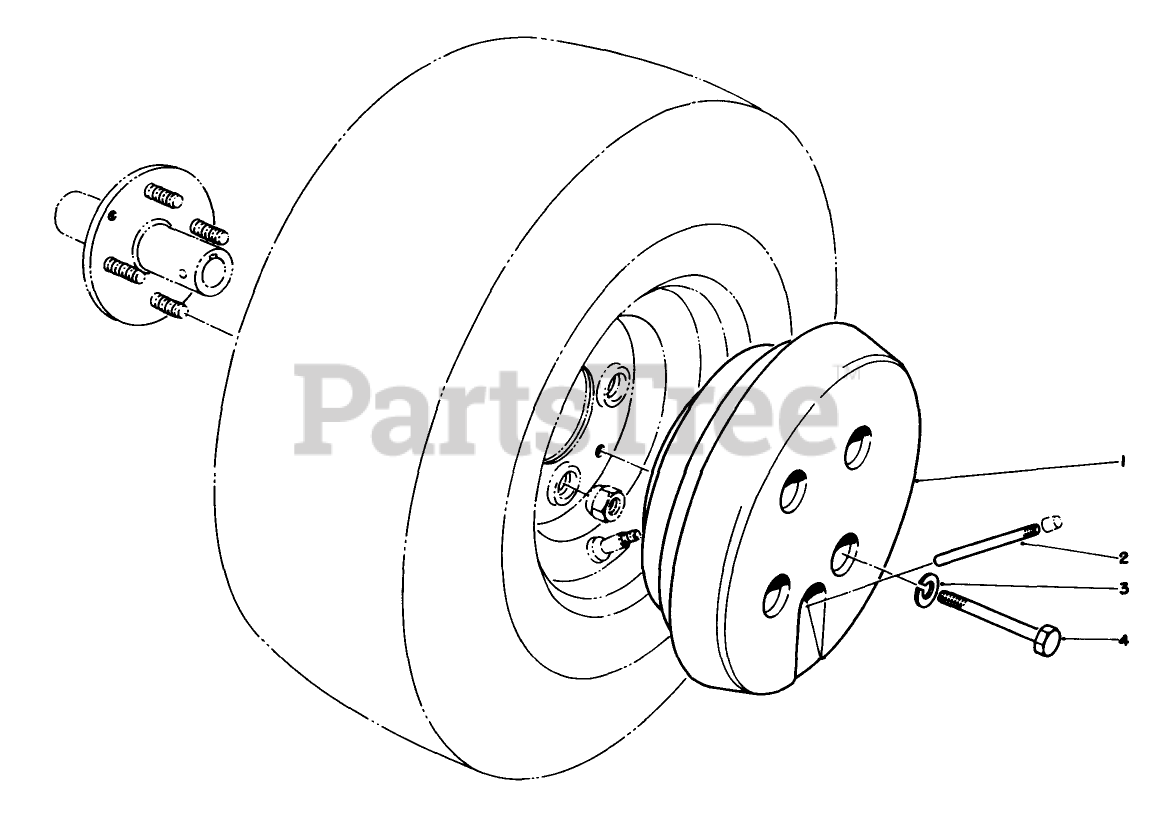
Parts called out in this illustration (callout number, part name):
2	VALVE EXTENSION
3	SCREW-HH
4	SCREW-HH
